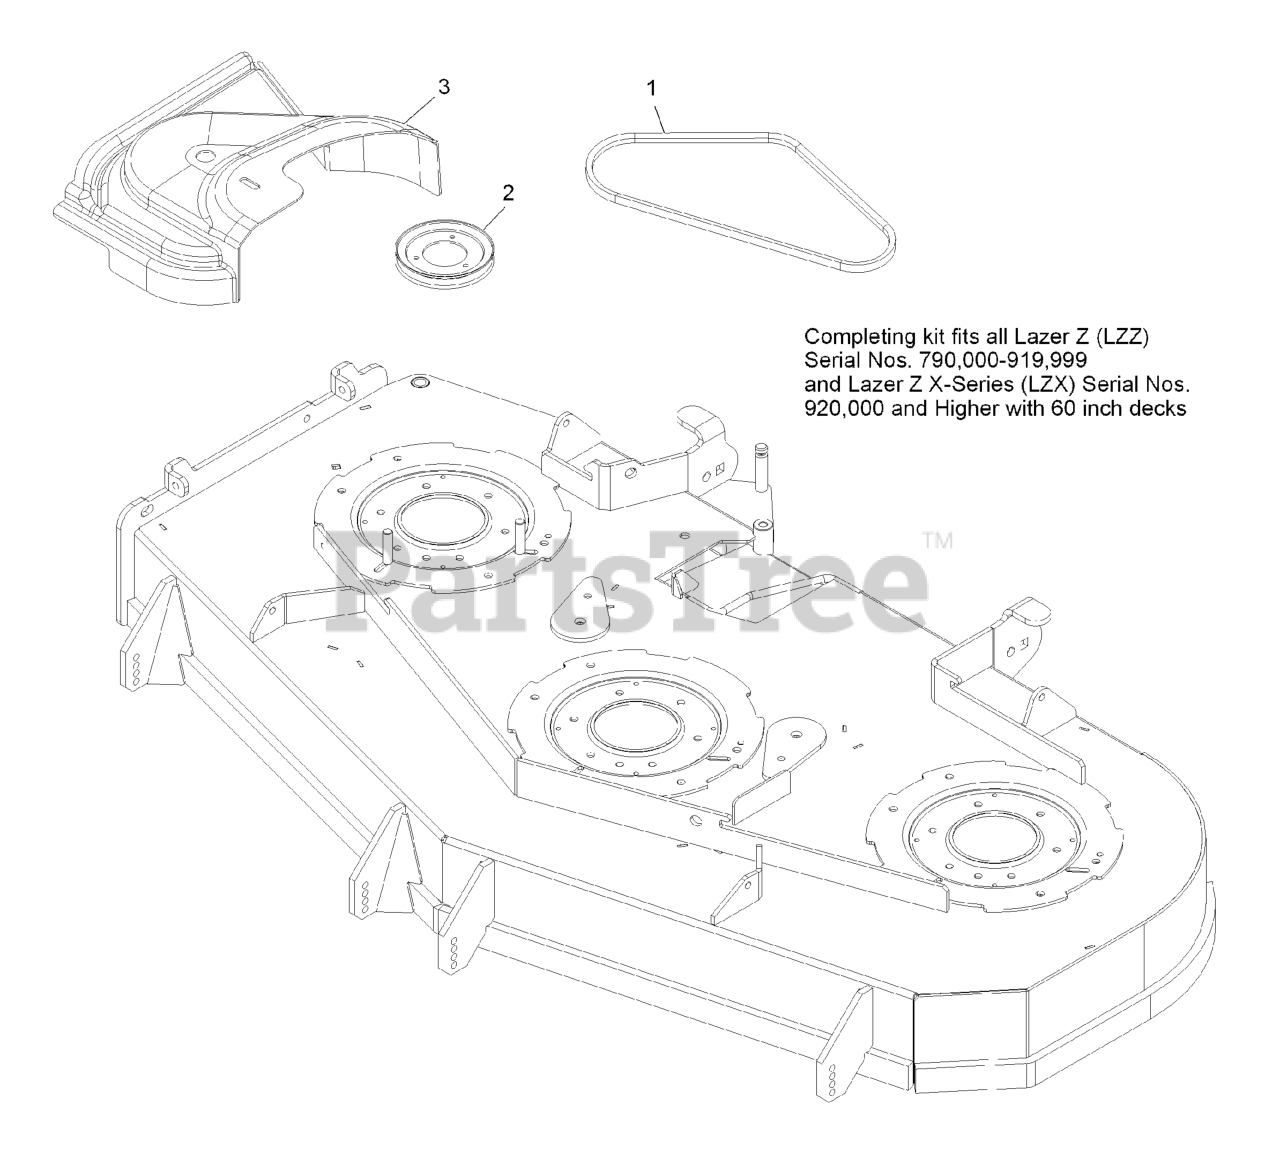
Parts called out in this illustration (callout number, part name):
1	BELT, BLOWER DRIVE 60
2	SHEAVE,DRIVE LZUV 606
3	COVER,BELT UV 60
